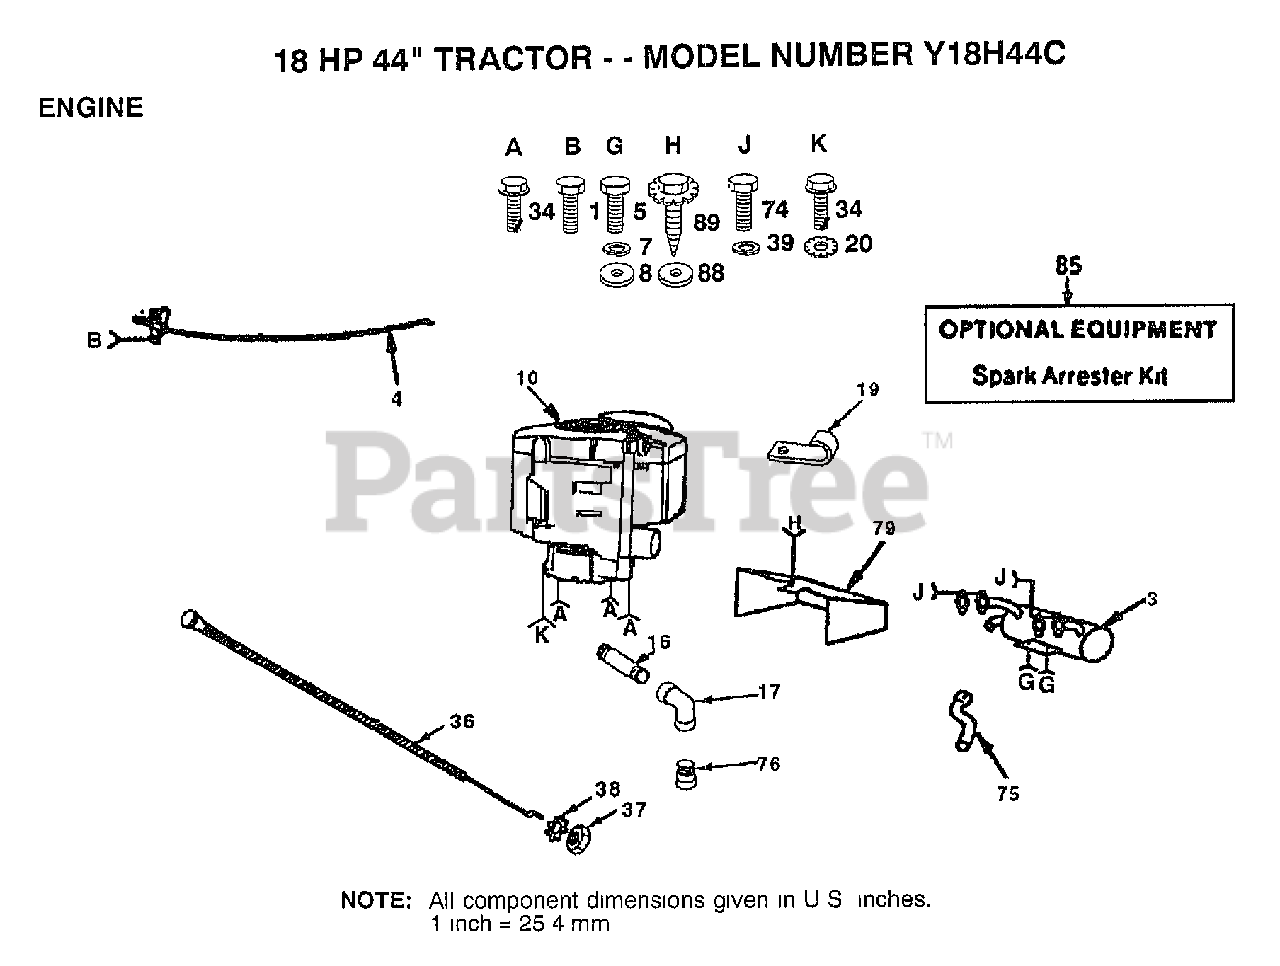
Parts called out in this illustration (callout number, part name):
1	SCREW LT
4	"CONTROL,THROTTLE"
7	LOCKWASHER
8	WASHER PM
16	PIPE NIPPLE LT
17	ELBOW
19	MUFFLER CLAMP
20	LOCKWASHER
34	SCREW LT
38	LOCKWASHER
39	LOCKWASHER
74	SCREW
85	SPARK ARREST KIT
